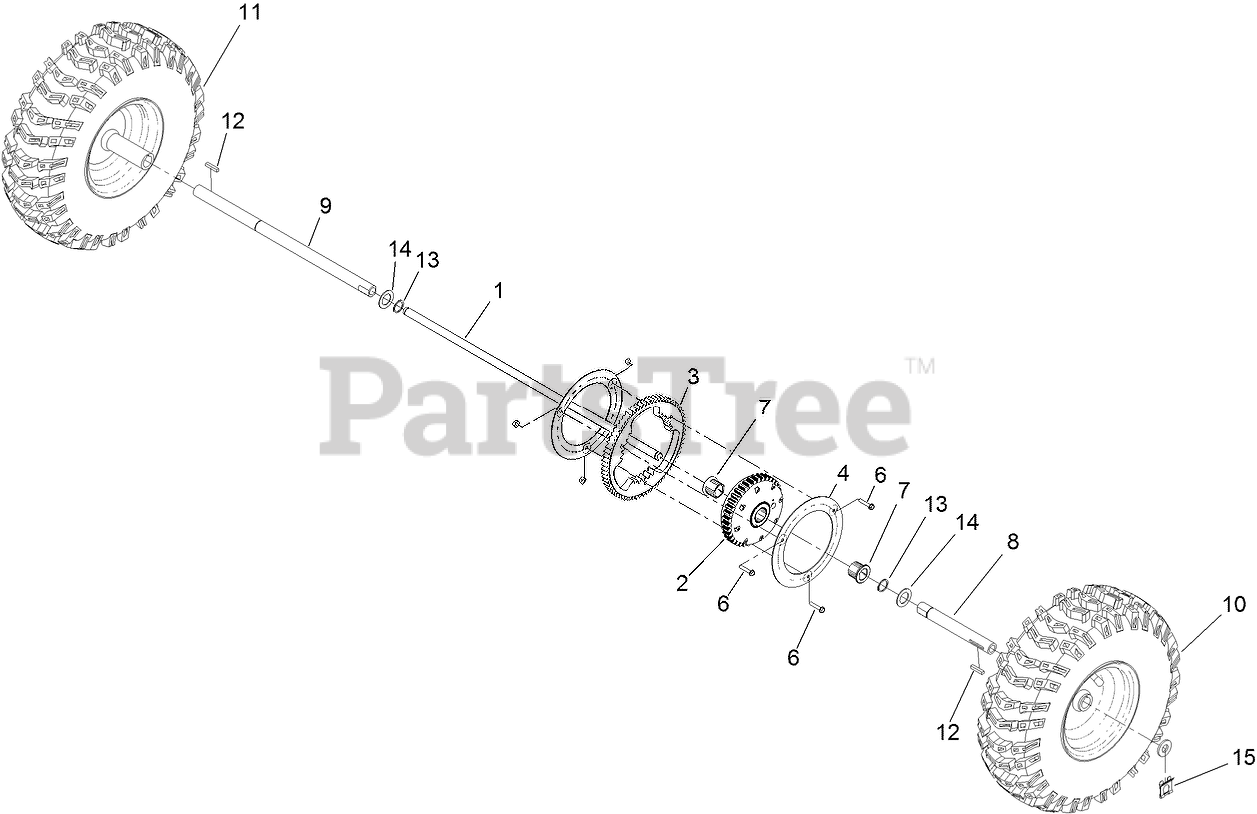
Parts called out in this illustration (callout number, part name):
2	TRANSMISSION
3	GEAR-AXLE
4	PLATE-GEAR
6	SCREW-HWH
7	GEAR-TUBE, AXLE
8	TUBE-AXLE
9	TUBE-AXLE
10	LH WHEEL AND TIRE ASM
11	RH WHEEL AND TIRE ASM
12	KEY-SQUARE
13	RING-SNAP
14	WASHER-THRUST
15	CLIP-PIN
